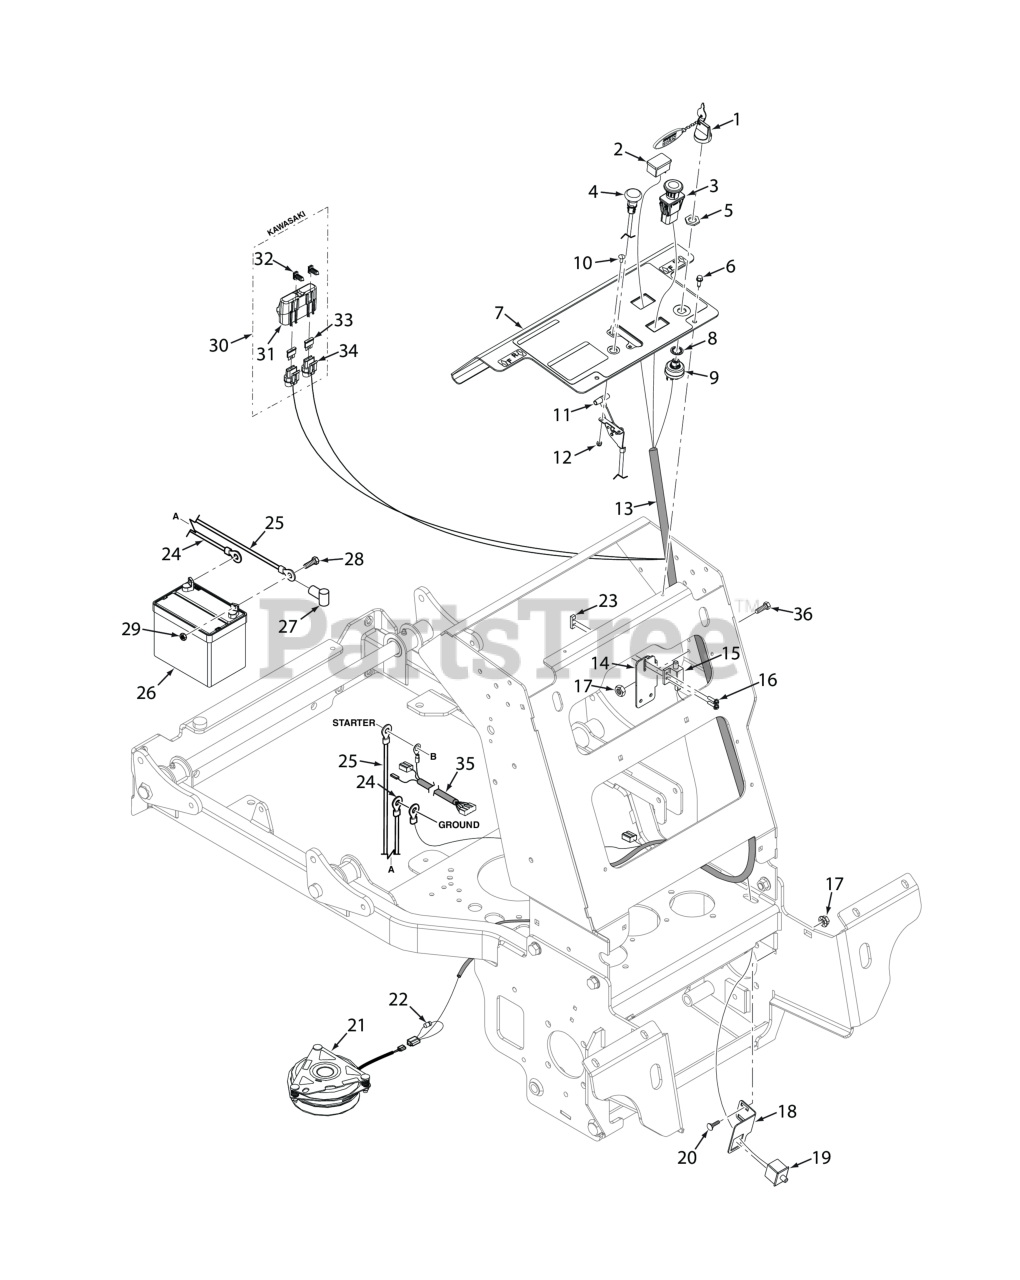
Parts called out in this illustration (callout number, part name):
1	Key, Assembly w/Fob
2	Hour Meter, Inductive
3	Switch, PTO - 10 Amp
4	Choke Control (excludes EFI models)
5	Nut, 5/8-32 Special
6	Screw, Self-Tapping 1/4-20 x 3/4
7	Instrument Panel w/Decal - SVRII36
8	LOCK WASHER, 5/8" INTERNAL TOOTH
9	KEY SWITCH(INCLUDES MOUNTING HARDWARE)
10	Bolt, Carriage #10-24 x 1/2"
11	Throttle Control, SVR
12	Nut, Elastic Stop #10-24
13	Wire Harness, SVRII-36
14	Bracket, Neutral Switch
15	Switch, Interlock (see below)
16	Screw, Hex-Slotted Washer Head #10 32 x 3/4"
17	NUT, 1/4-20 SERRATED FLANGE HEX HEAD
18	Switch Bracket, OPC Switch -SVRII-36
19	Switch, Double Pole OPC - SVRII-36
20	Serr. Fl. Hex Head CPSCR, 1/4-20 x 3/4"
21	Clutch w/Tag GT2.5-FE02 (48 / 52)
22	Diode, 600V 6 Amp
23	Plate, Threaded
24	Battery Cable, 39" Black (26EFI) - Kohler
25	Battery Cable, 44" Red w/Braid (26EFI) - Kohler
26	Battery, 350 CCA (not available through Scag)
27	RUBBER BOOT
28	BOLT, HEX HEAD, 1/4-20 X 3/4 GR.5
29	Nut, 1/4 - 20 Hex
30	Double Fuse Assy.
31	Cover, Sealed Double
32	Clip, Fuse Holder
33	FUSE, 20 AMP BLADE TYPE AUTOMOTIVE
34	Fuse Holder Assembly
35	Wire Harness Adapter, Kawasaki FX & FT
36	BOLT, HEX HEAD, 1/4-20 X 3/4 GR.5
